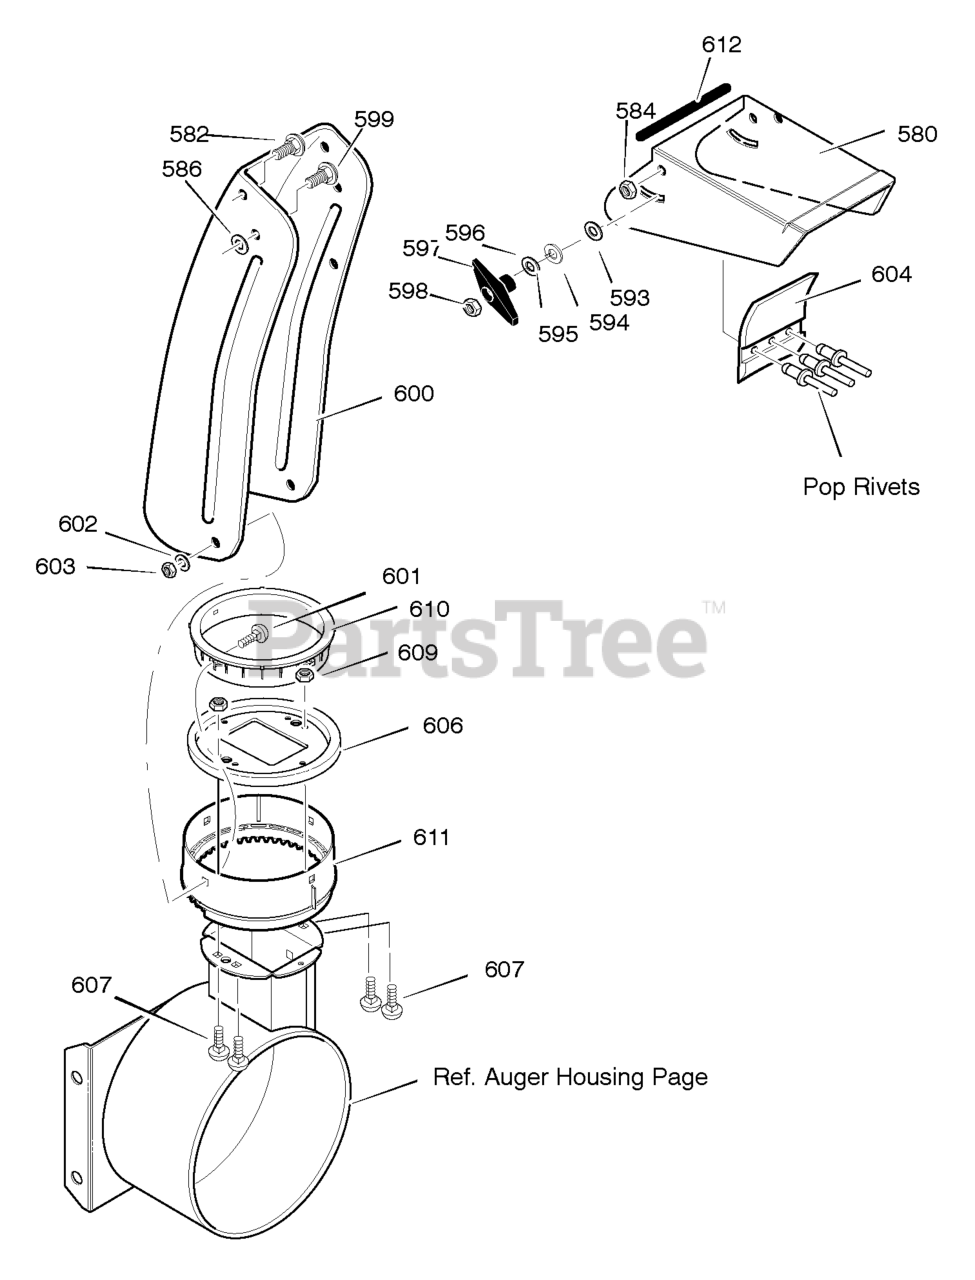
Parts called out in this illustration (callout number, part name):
580	CHUTE, UPPER W/REMOTE
582	SCREW, 5/16-18 x 0.75
584	NUT
586	WASHER, PLASTIC
593	WASHER, PLASTIC
594	WASHER, FLAT
595	WASHER, SPLIT
596	WASHER, FLAT
597	KNOB, T 3.00
598	NUT
599	SCREW, 5/16-18 x 0.75
600	CHUTE, LOWER / GUARD
602	WASHER, FLAT
603	NUT
606	CHUTE COLLAR
607	BOLT
609	NUT
610	RETAINER, RING INNER
611	RETAINER, RING OUTER
